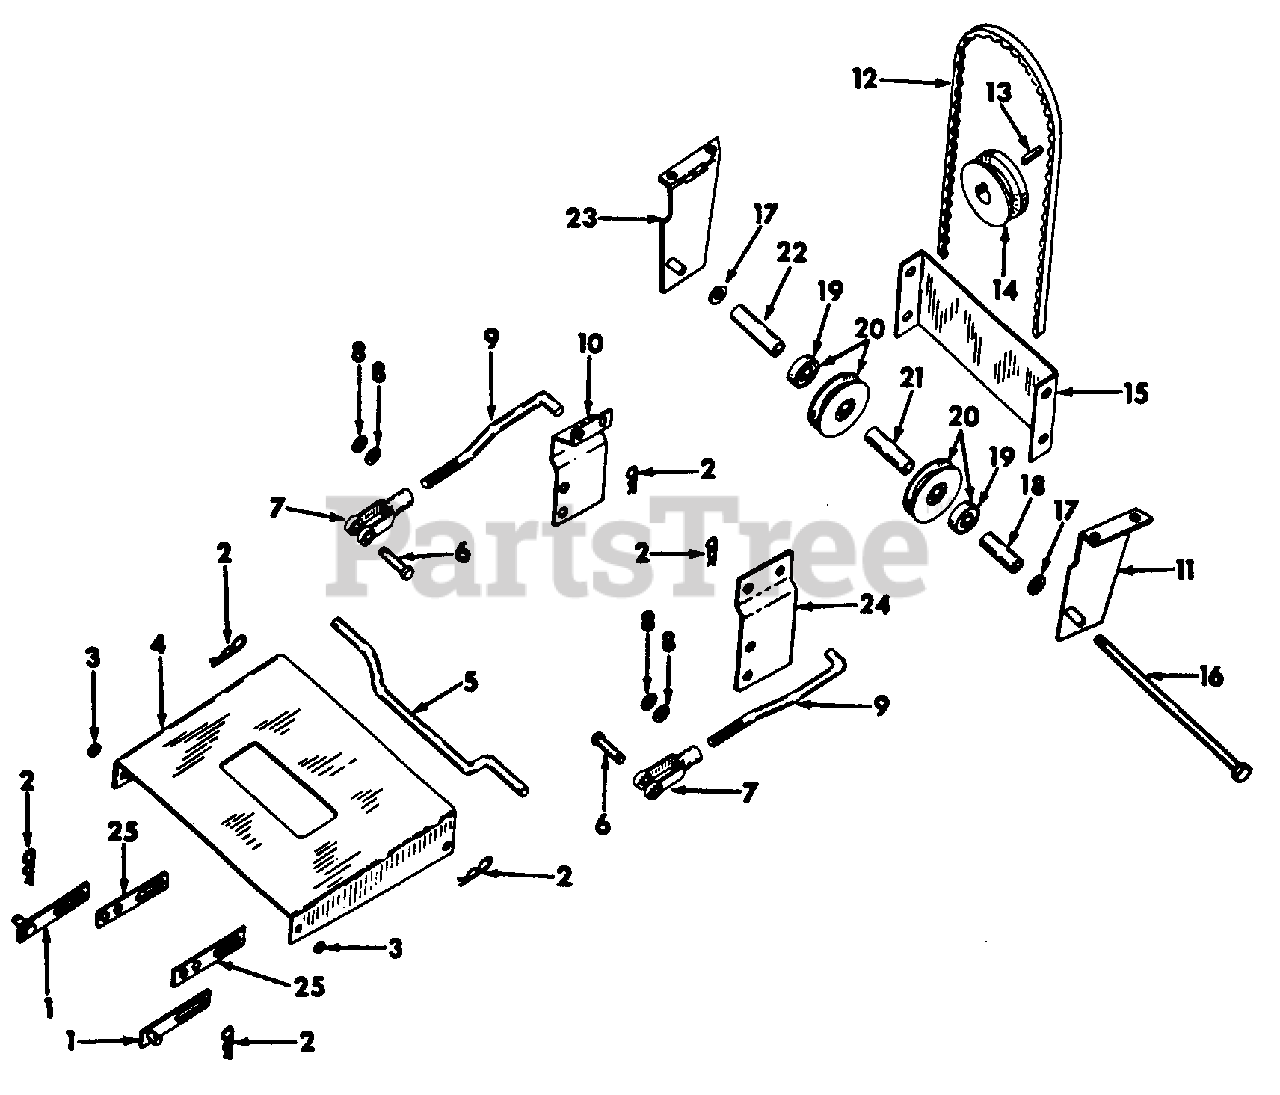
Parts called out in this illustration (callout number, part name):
1	Link Assy, Lift
2	Pin, Quick Attachable Cotter
4	Link Assy, Lower Parallel
5	Rod, Lower Link Pivot
6	Pin, Rod End Clevis
7	Clevis, Rod End 1/2-20
8	Washer, 17/32 X 7/8 X 8 Ga
9	Rod, Upper Link
10	Strip, LH Link
11	Support, Tightener RH
12	Belt, Drive
13	Key, 1/4 Sq X 1 Parallel
14	Pulley, Engine
15	Shield, Front Pulley
16	Bolt, 5/8-11 X 7-1/2 C-Z Hex-Hd Mach
17	Washer, .656 X 1.250 X .090 Pln
18	Spacer, Right Idler
19	Bearing, Pulley Ball
20	Pulley Assy, Tightener
21	Spacer, Center Idler
22	Spacer, Left Idler
23	Support, Tightener LH
24	Strip, RH Link
25	Strip, Lift
